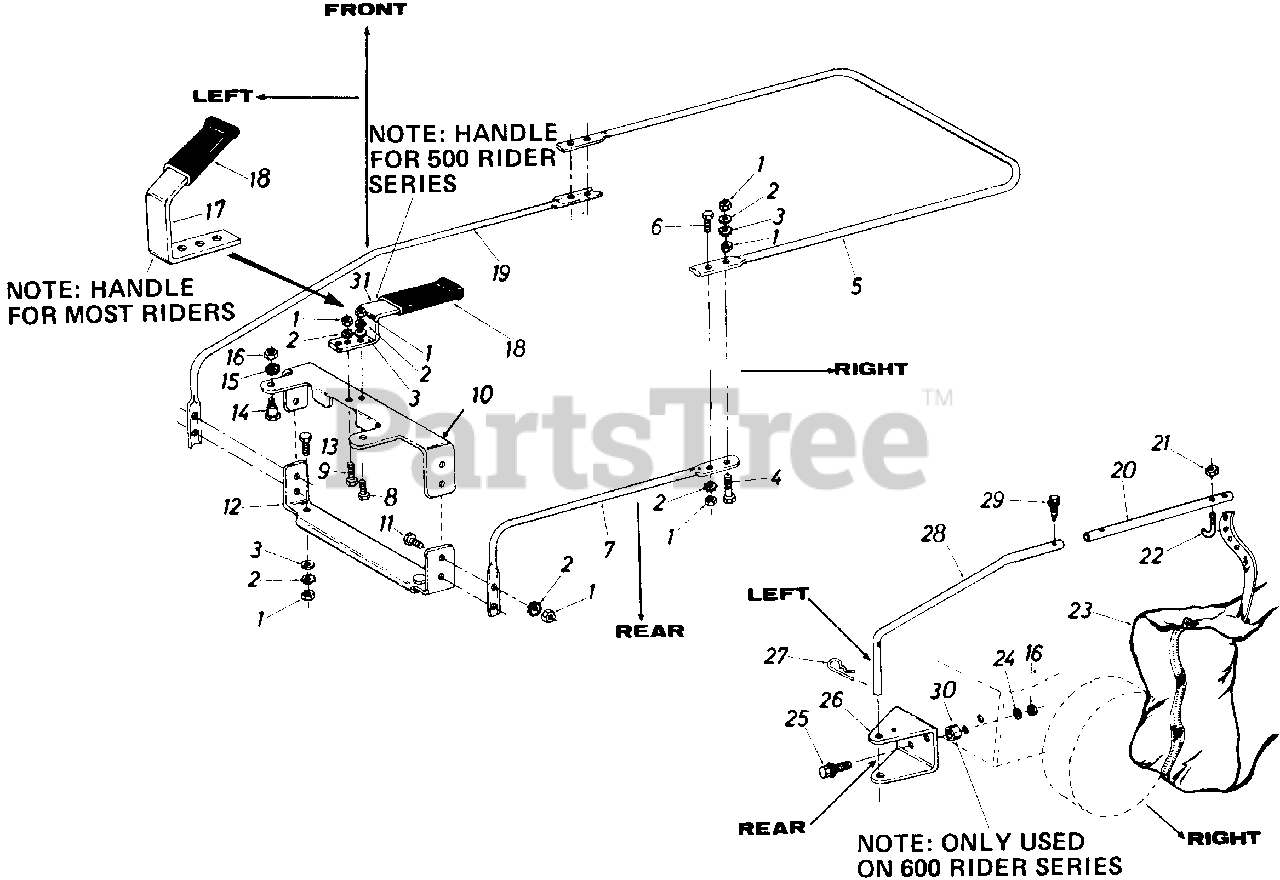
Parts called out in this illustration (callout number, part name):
1	Hex Nut 1/4-20 Thd.*
2	Ext. L-Wash. 1/4" Scr.*
3	Fl-Wash. .281 I.D. x .50 O.D.
4	Hex Scr. 1/4-20 x 1.50" Lg.*
5	Upper Frame Half
6	Hex Scr. 1/4-20 x 1.00" Lg.
7	Lower Frame Tubing
8	Hex Scr. 1/4-20 x .75" Lg.
9	Hex Scr. 1/4-20 x .75" Lg.*
10	Upper Opening Support
11	Hex Scr. 1/4-20 x 1.0" Lg.*
12	Lower Opening Support
13	Hex Scr. 1/4-20 x .50" Lg.*
14	Shld. Scr. .437 Dia. x .350
15	Ext. L-Wash. 5/16" Scr.*
16	Hex Nut 5/16-18 Thd.*
17	Handle
18	Grip-Black
19	Lower Frame Arm
22	Hook
23	Grass CatcherBag
24	L-Wash. 5/16" I.D.*
25	Hex Sems Scr. 5/16-18 x .75" Lg.*
25	Hex Sems Bolt 5/16-18 x 1.50" Lg.*
26	Hitch Bracket
27	Internal Cotter Pin 5/8" Dia.
28	Lower Holding Arm
29	Hex Wash. Hd. Self-Tap .50" Lg.
30	Spacer
31	Handle
